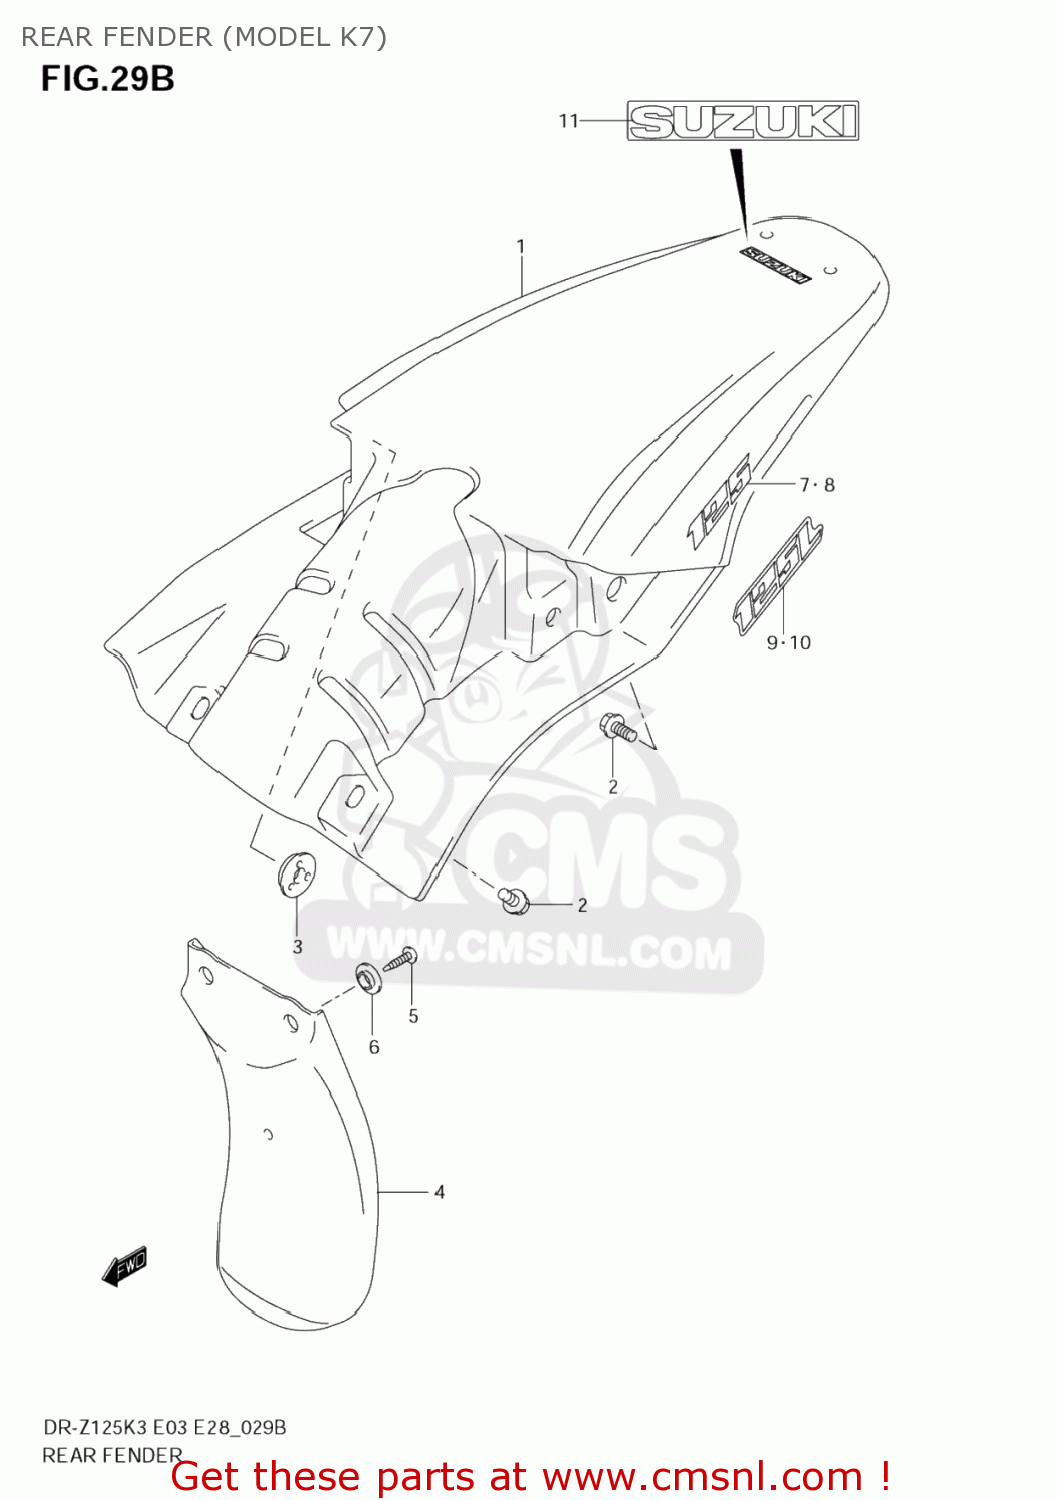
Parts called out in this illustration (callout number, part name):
1	FENDER,RR
2	BOLT
3	WASHER
4	MUDGUARD,RR FENDER FR
5	SCREW
6	WASHER
7	EMBLEM,125,R
8	EMBLEM,125,L
9	EMBLEM,125,R
10	EMBLEM,125,L
11	EMBLEM
